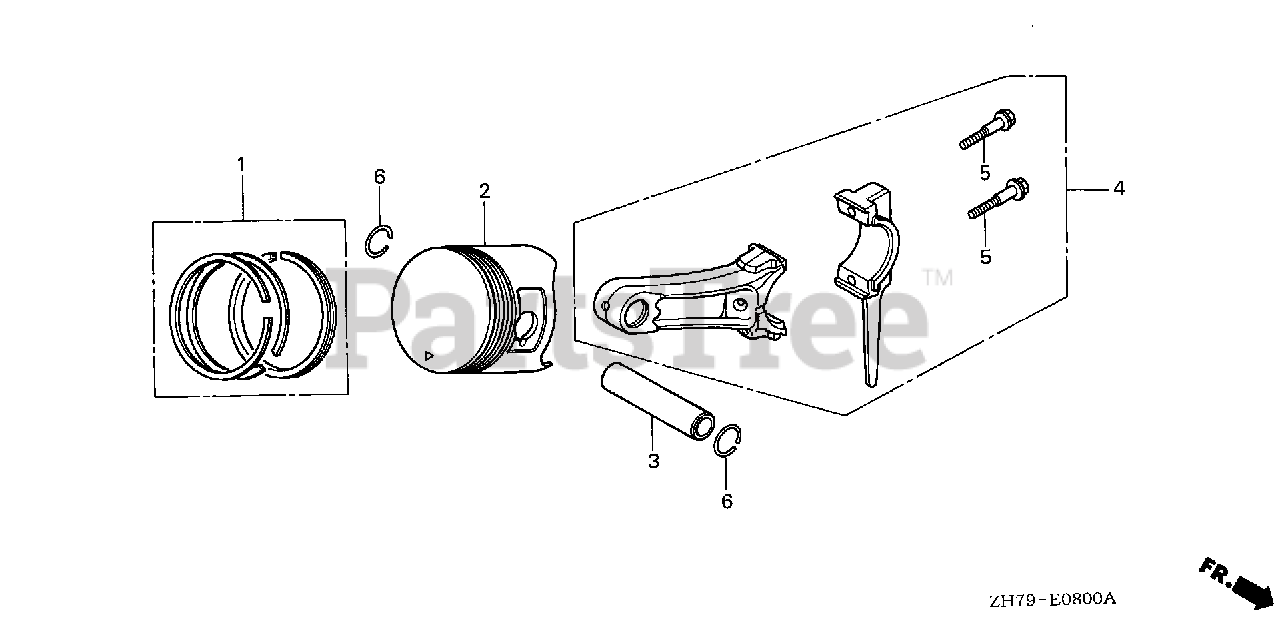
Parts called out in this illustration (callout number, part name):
1	RING SET, PISTON (STD) (TEIKOKU)
1	RING SET, PISTON (STD) (NIPPON)
1	RING SET, PISTON (OS 0.25) (TEIKOKU)
1	RING SET, PISTON (OS 0.25) (NIPPON)
1	RING SET, PISTON (OS 0.50) (TEIKOKU)
1	RING SET, PISTON (OS 0.50) (NIPPON)
1	RING SET, PISTON (0.75) (TEIKOKU)
1	RING SET, PISTON (0.75) (NIPPON)
2	PISTON (STD)
2	PISTON (OS 0.25)
2	PISTON (OS 0.50)
2	PISTON (0.75)
3	PIN, PISTON
4	ROD ASSY., CONNECTING (UNDER SIZE)
4	ROD ASSY., CONNECTING
5	BOLT, CONNECTING ROD
6	CLIP, PISTON PIN (13MM)
